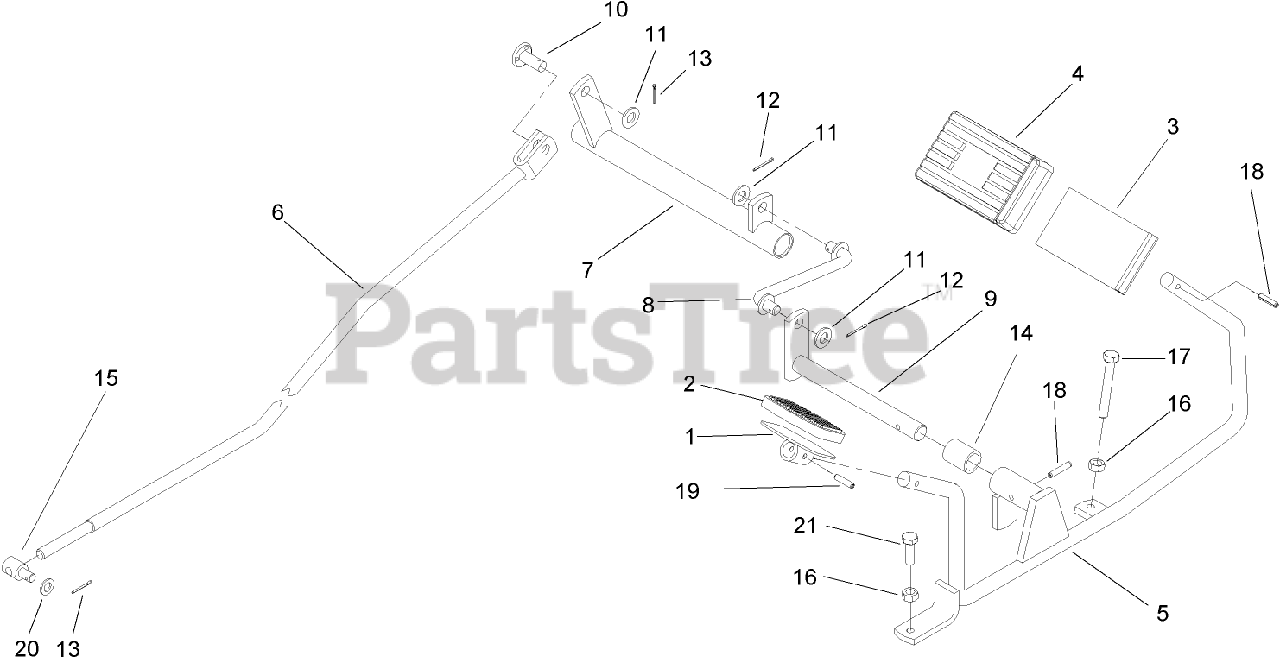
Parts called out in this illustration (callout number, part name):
2	PAD-PEDAL
4	PAD-PEDAL, FRONT
5	ROD-TRAVEL
6	ROD-TIE
7	SHAFT-DIAGONAL
8	LINK-FORMED
9	SHAFT-DIAGONAL
11	WASHER-FLAT
12	PIN-COTTER
13	PIN-COTTER
14	SPACER
16	NUT-HEX
17	SCREW-HH
18	PIN-SPRING
19	PIN-SPRING
20	WASHER
21	SCREW-HH
